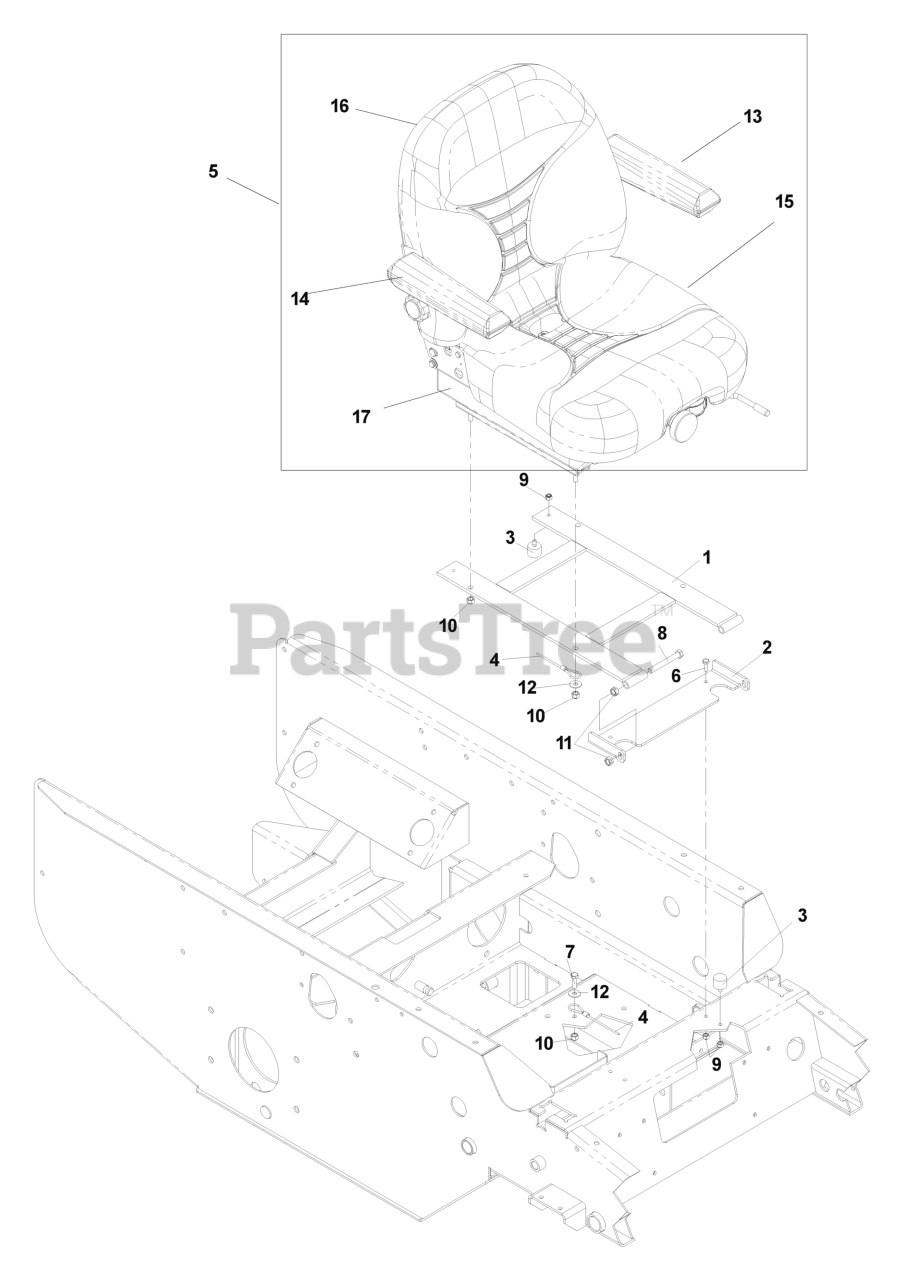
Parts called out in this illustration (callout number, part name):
1	SEAT MOUNT
2	SEAT BKT. W/PAINT
3	STUD/PLATE MOUNT
4	SEAT LANYARD
5	Seat suspension
6	HCS 1/4C X 3/4 HCS
7	HCS 5/16C X 1
8	HCS 3/8C X 3
9	NUT.1/4-20.HEX.NYLOC.ZD
10	NUT 5/16 NYLOC
11	NUT 3/8C CENTERBLOCK
12	WASHER 5/16 FLAT
13	ARMREST KIT, LH
14	ARMREST KIT, RH
15	SEAT CUSHION KIT
16	BACK CUSHION KIT
17	SLIDE KIT, SEAT ADJ
